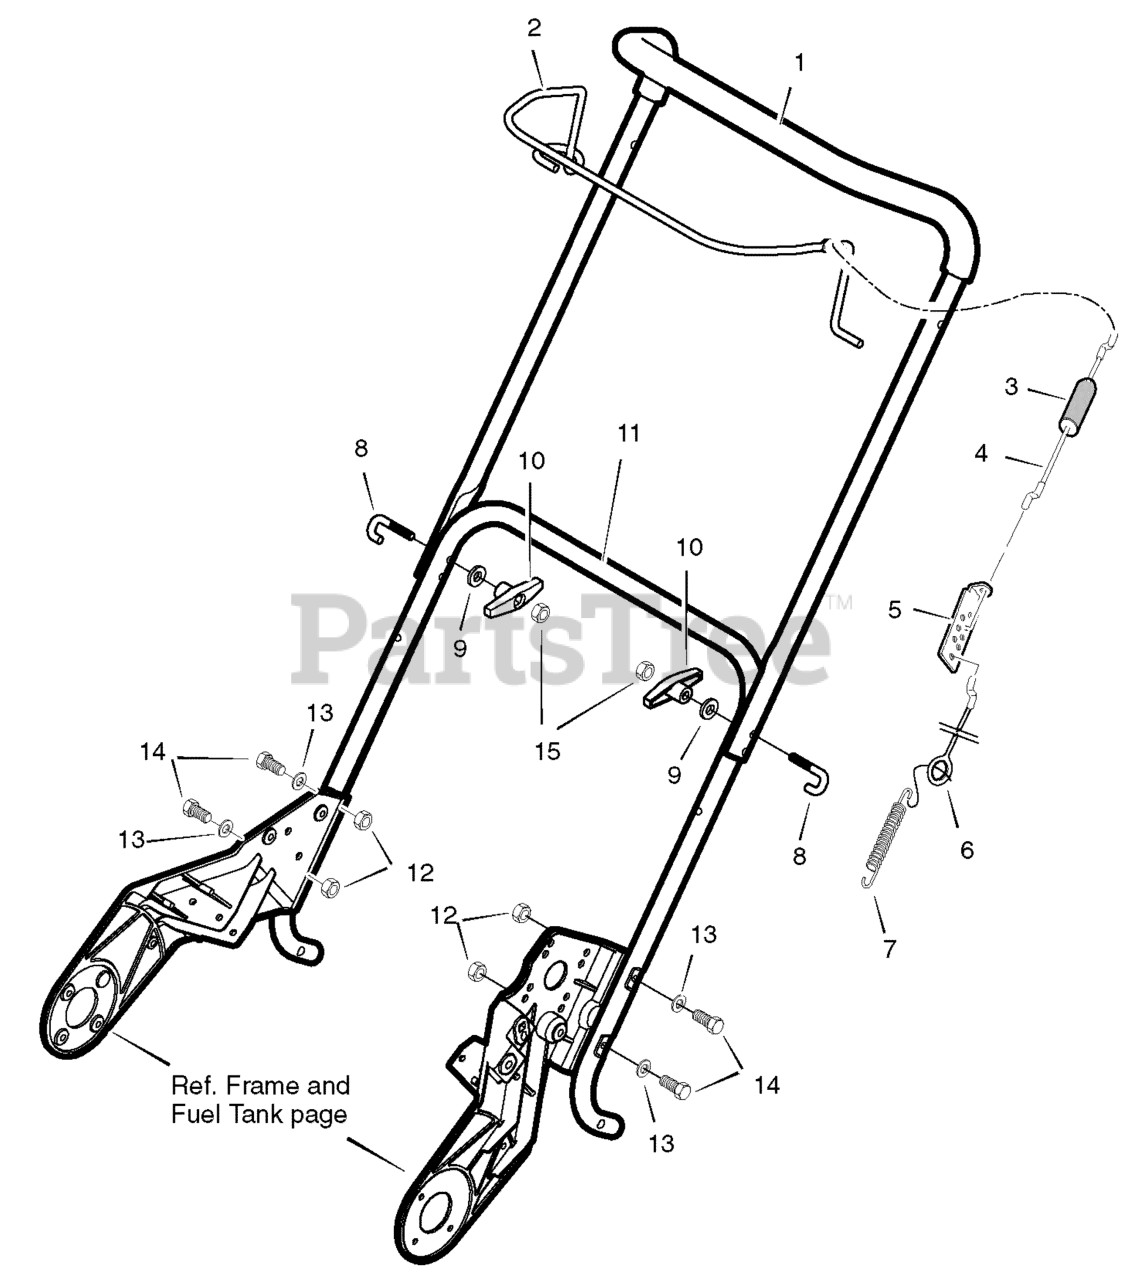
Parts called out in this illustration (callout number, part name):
1	Handle & Grip Assembly
2	Control, Bail
3	Boot, Clutch Spring
4	Cable, Upper Control
5	Bracket, Control Adjust
6	Cable, Lower Control
7	Spring
8	U-Bolt
9	Washer
10	Knob, Wing
11	Handle, Lower
13	Washer
14	Screw, 1/4-20 x1.25
15	Nut, 5/16-18
